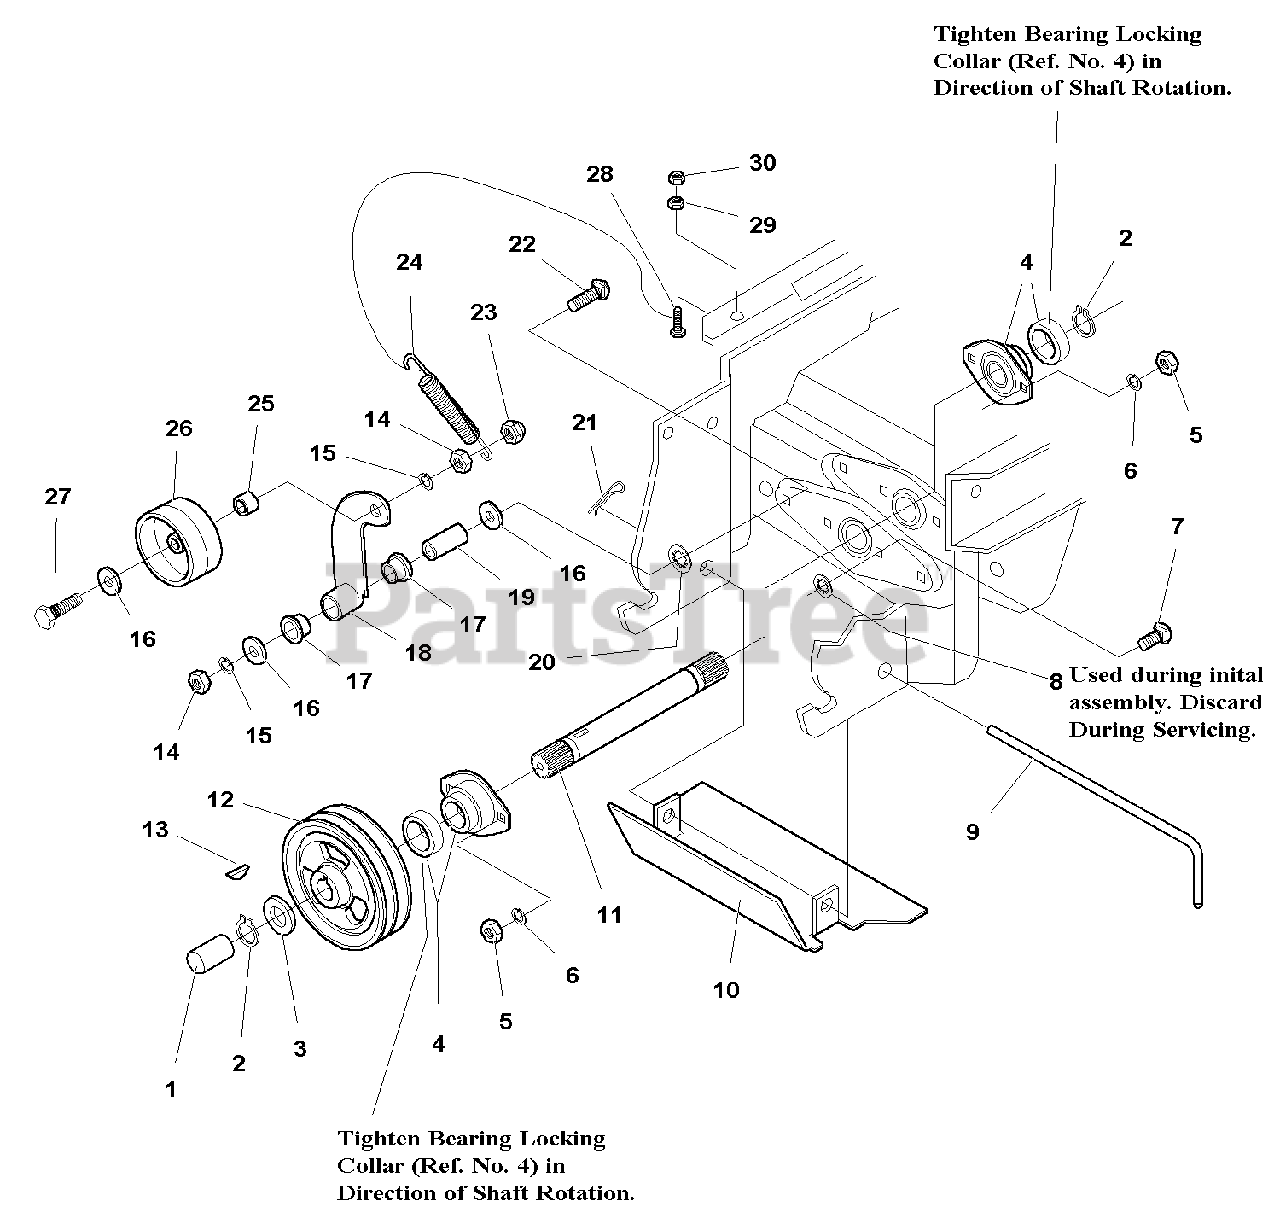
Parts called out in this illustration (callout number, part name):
1	COVER, P.T.O. Shaft
2	RING, Retainer
3	WASHER, 1.0
4	BEARING, Ball
5	NUT, Hex, Full, 5/16-18
6	LOCKWASHER, 5/16
7	CARRIAGE BOLT, 5/16-18 x 7/8
8	NUT, Push, Used for initial assembly only, Discard During Service.
9	PIN, 1/2 x 12
10	GUARD PLATE, P.T.O.
11	SHAFT, P.T.O.
12	PULLEY, P.T.O., Double
13	KEY, Hi Pro, 3/4 Dia.
14	NUT, Hex, Full, 3/8-16
15	LOCKWASHER, 3/8
16	WASHER, 13/32
17	BUSHING, 41/64 x 3/4 x 1/2
18	ARM ASSEMBLY, Idler
19	SPACER, 25/64 x 5/8 x 1-1/2
20	NUT, Push, 3/8
21	HAIRPIN, Cotter
22	CARRIAGE BOLT, 3/8-16 x 2-1/4
23	NUT, Hex, Flange Lock, 3/8-16
24	SPRING, Tension
25	SPACER, 25/64 x 5/8 x 5/8
26	PULLEY, Idler, 3-1/4 Dia.
27	CAPSCREW, Hex Head, 3/8-16 x 2-1/2
